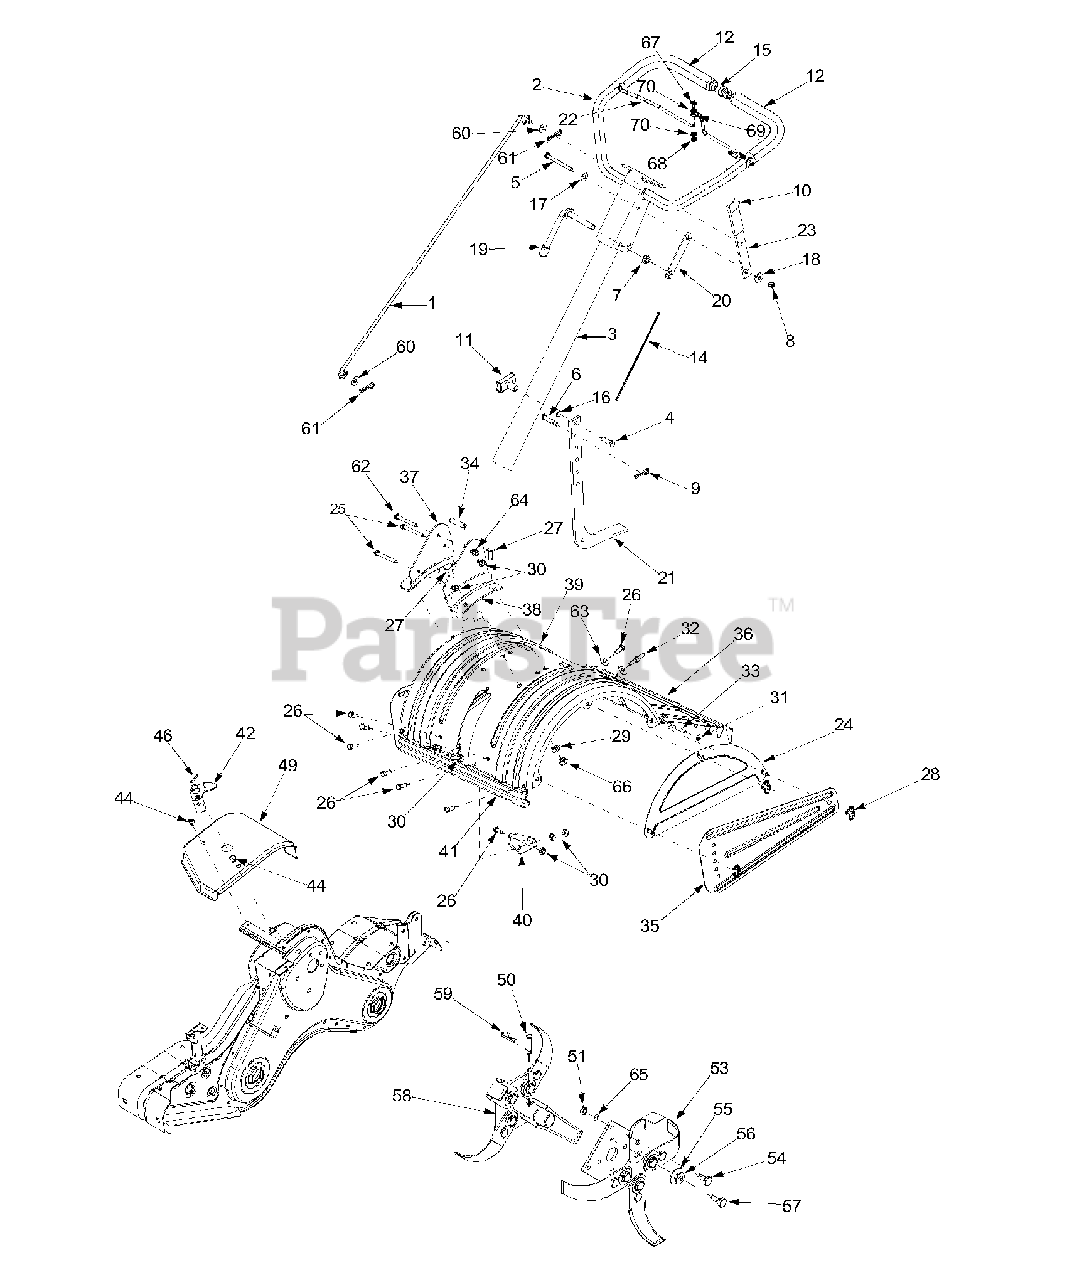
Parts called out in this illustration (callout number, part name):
1	Shift Rod
4	Hex Screw 3/8-16 x 1.25
5	Hex Screw 5/16-18 x 3.25
6	Clevis Pin 3/8-1.62
7	Flange Lock Nut 3/8-24
8	Hex Lock Nut 5/16-18
9	Cotter Pin
11	T-Knob
12	Foam Grip
14	Cable Tie
15	Plug
16	Flat Washer 3/8 ID x .620 OD
17	Bell Washer .340 ID x .872 OD
18	Shoulder Spacer
19	Handle Adjustment Crank
20	Hex Nut Retainer Bracket
25	Hex Cap Screw 5/16-18 x 2.75
26	Hex Cap Screw 5/16-18 x .750
27	Carriage Bolt 3/8-16 x 1.0
28	Wing Nut
29	Lock Washer 3/8
30	Flange Nut 5/16-18
31	Cap Nut
32	Hex Screw 5/16-18 x .75"
34	Spacer .435 OD x .322 ID
42	Shift Crank Ass'y
44	Screw 1/4-14 x .625
46	Spiral Pin 3/16 x 1.0
51	Hex Nut 3/8-24
54	Shoulder Bolt
55	Flat Washer .51" ID x 1.50" OD
56	Bell Washer .515" ID x 1.14" OD
57	Shoulder Bolt
59	Internal Cotter Pin
60	Rubber Washer
61	Cotter Pin
62	Hex Screw 3/8-16 x 2.75"
63	Flat Washer
64	Flange Nut .344 ID x .62 OD
65	Lock Washer
66	Hex Nut 3/8-16
67	Truss Screw 1/4-20 x .65
68	Hex Lock Nut 1/4-20
69	Battery Hose Clamp 5/16
70	Flat Washer .260 ID x .720 OD
